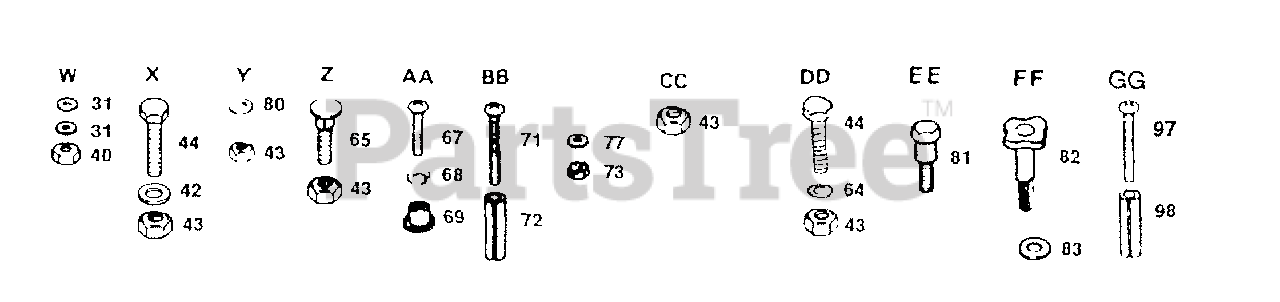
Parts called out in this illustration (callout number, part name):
31	Washer 9/32 x 3/4 x 16 Ga.
40	Nut-Hex 1/4-20
42	Washer 13/32 x 13/16 x 12 Ga.
43	Nut-Crownlock 3/8-16
44	Bolt-Hex 3/8-16 x 1
64	Washer 13/32 x 1 - 1/4 x 12 Ga.
65	Bolt - Carriage 3/8 - 16 x 3/4
67	Screw - Cross Recess Pan Hd. Mach. 10 - 24 x 1/2
68	Washer - Lock No. 10
69	Nut - Weld
71	Screw - Machine Cross Recess 10 -24x1-1/4
72	Spacer - Split 10 x 3/4
73	Nut - Keps 10 - 24
77	Washer 7/32 x 1/2 x 18 Ga.
80	Washer 13/32 x 1 x 14 Ga.
81	Shoulder - Bolt 5/16 x 18 UNC
82	Knob - 1/2
83	Washer 17/32 x 13/16 x 12 Ga.
97	Bolt, 1/4 - 20 x 2 1/2
